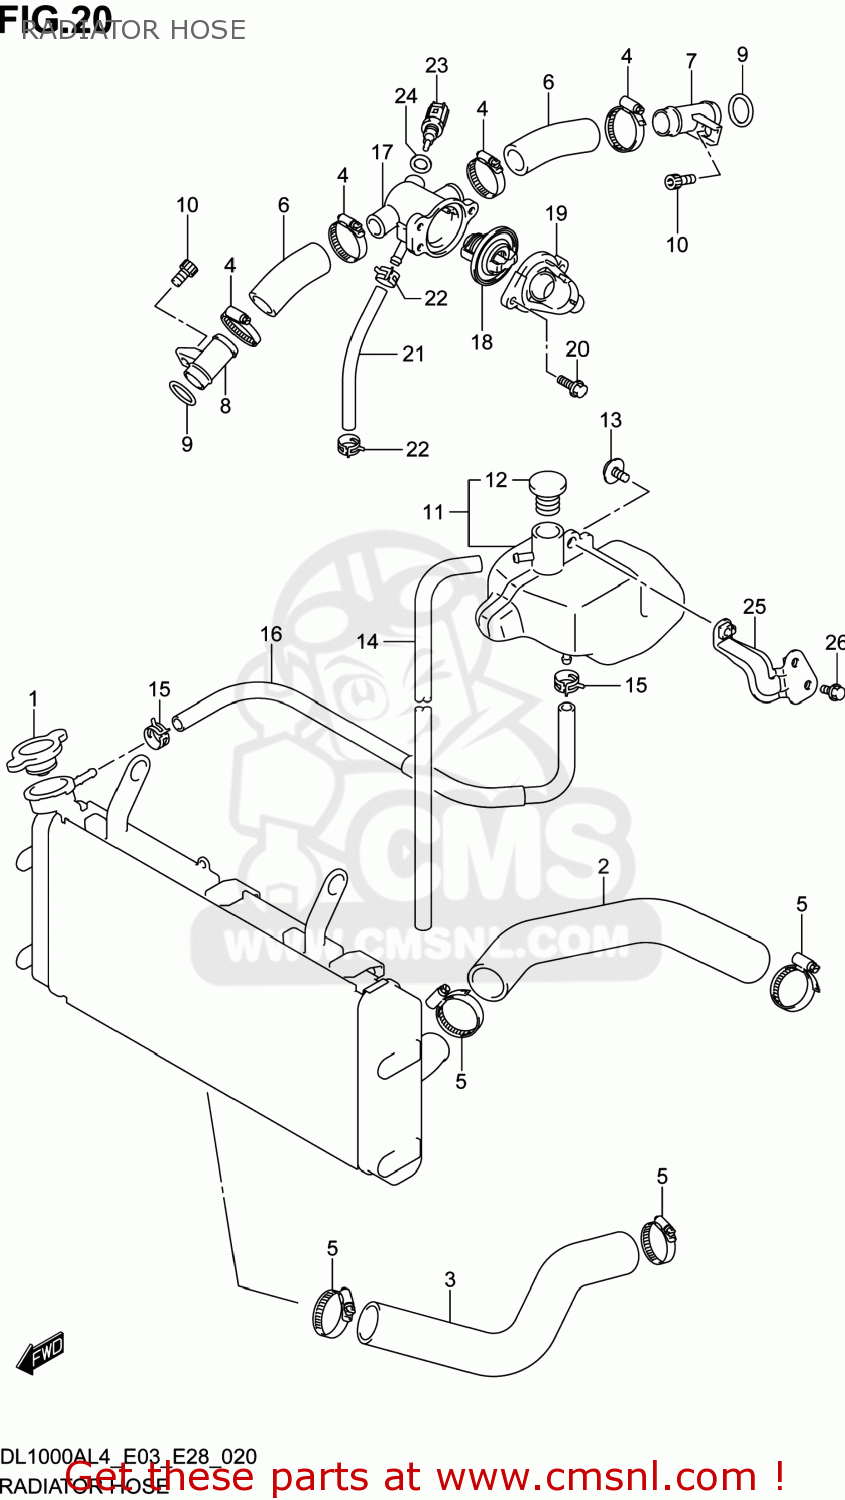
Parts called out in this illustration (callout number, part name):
1	CAP,RADIATOR(1.1)
2	HOSE,RADIATOR INLET
3	HOSE,RADIATOR OUTLET
4	CLAMP
5	CLAMP
6	HOSE,CONNECTOR INLET
7	UNION,CONNECTOR HOSE
8	UNION,CONNECTOR HOSE
9	O RING(D:3.2,ID:17.8)
10	BOLT
11	TANK ASSY,RESERVOIR
12	CAP,WATER RESERVOIR TANK
13	BOLT(6X12)
14	HOSE,RSVR TANK OVFL
15	CLIP
16	HOSE,RSVR TANK INLET
17	CONNECTOR,THERMOSTAT INLET
18	THERMOSTAT,WATER
19	CAP,THERMOSTAT CONNECTOR
20	BOLT
21	HOSE,WATER BYPASS
22	CLAMP
23	SENSOR,TEMP
24	GASKET(12X17X1) (NAS)
25	BRACKET,RSVR TANK
26	BOLT
